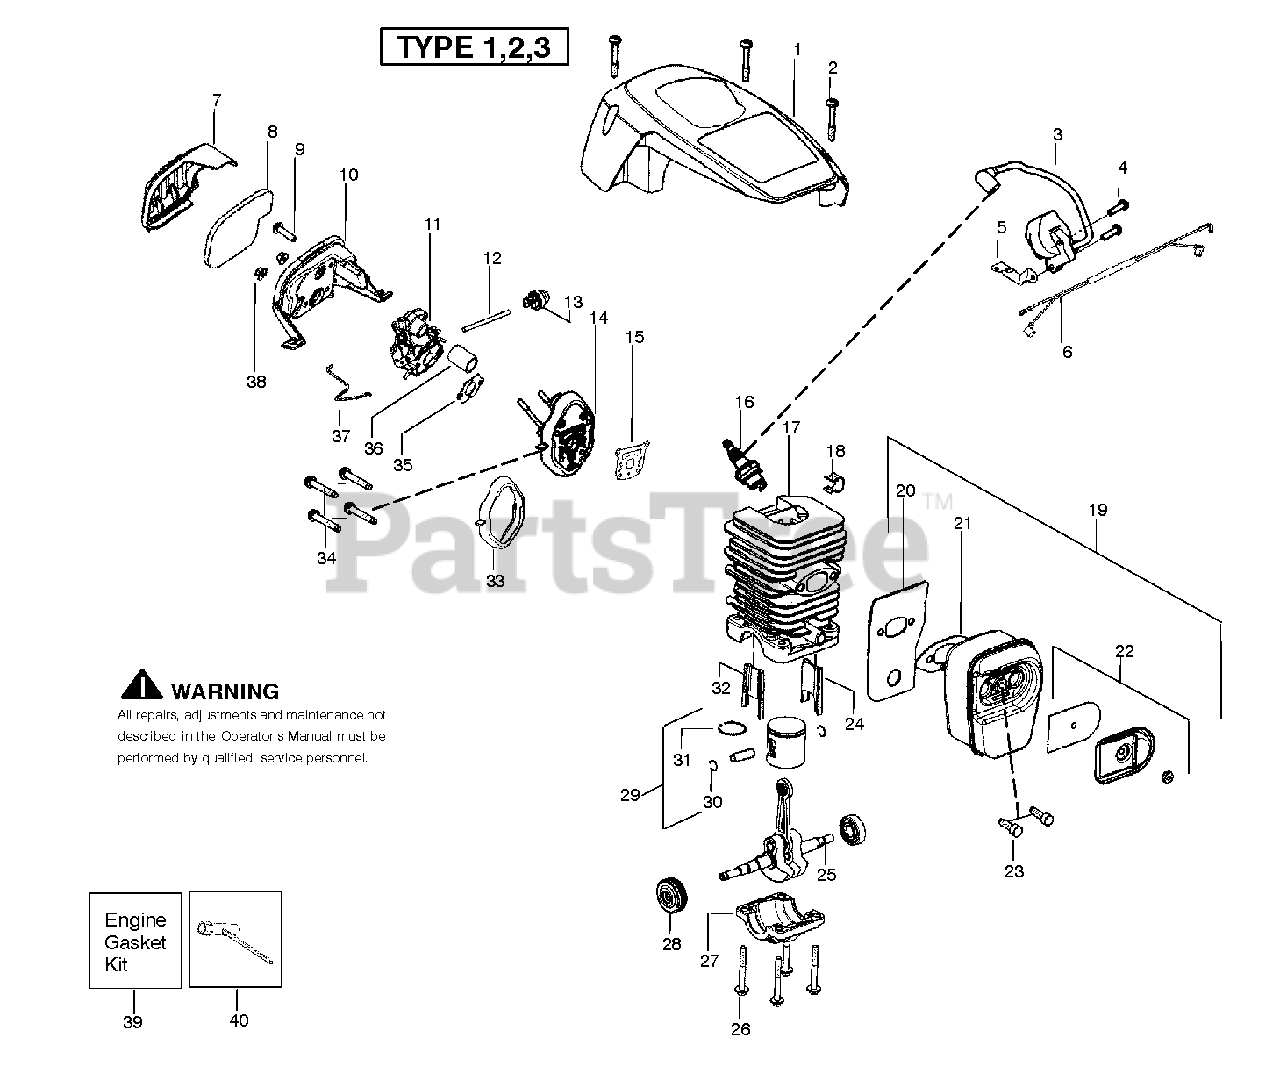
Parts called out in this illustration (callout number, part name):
1	SHIELD CYLINDER BLACK
4	SCREW M5.38-14X22.225MM
5	GROUND STRAP
6	ASSY WIRE HARNESS
7	COVER, AIR FILTER
8	FILTER AIR
9	SCREW M5-0.8X16
10	HSG FILTER
11	CARB ZAMA W26B W/PURGE
12	KIT-LINE
13	AIR PURGE
14	KIT CARB ADAPTOR
15	KIT GASKET SAS
16	SPARK PLUG (RCJ-7Y)
17	KIT CYLINDER
18	CLIP-HIGH TENSION LEAD
19	KIT MUFFLER SAS NON CAT
20	PLATE BACK MUFFLER
21	KIT GASKET SAS
22	KIT SPARK ARRESTOR SAS NCAT
23	SCREW MUFFLER
24	INSERT TRANSFER LEFT
25	CRANKSHAFT & ROD ASSY
26	BOLT M6-1.0 X 25MM
27	CRANKCASE CASTING
28	BEARING & SEAL ASSEMBLY
29	KIT PISTON
30	C-CLIP,PSTN PIN 36/41
31	PISTON RING 42CC
32	INSERT TRANSFER RIGHT
33	KIT GASKET SAS
34	SCREW M5-0.8X30MM
35	KIT GASKET SAS
36	TUBE INTAKE
37	WIRE THROTTLE
39	KIT GASKET SAS
40	WRENCH-BAR
